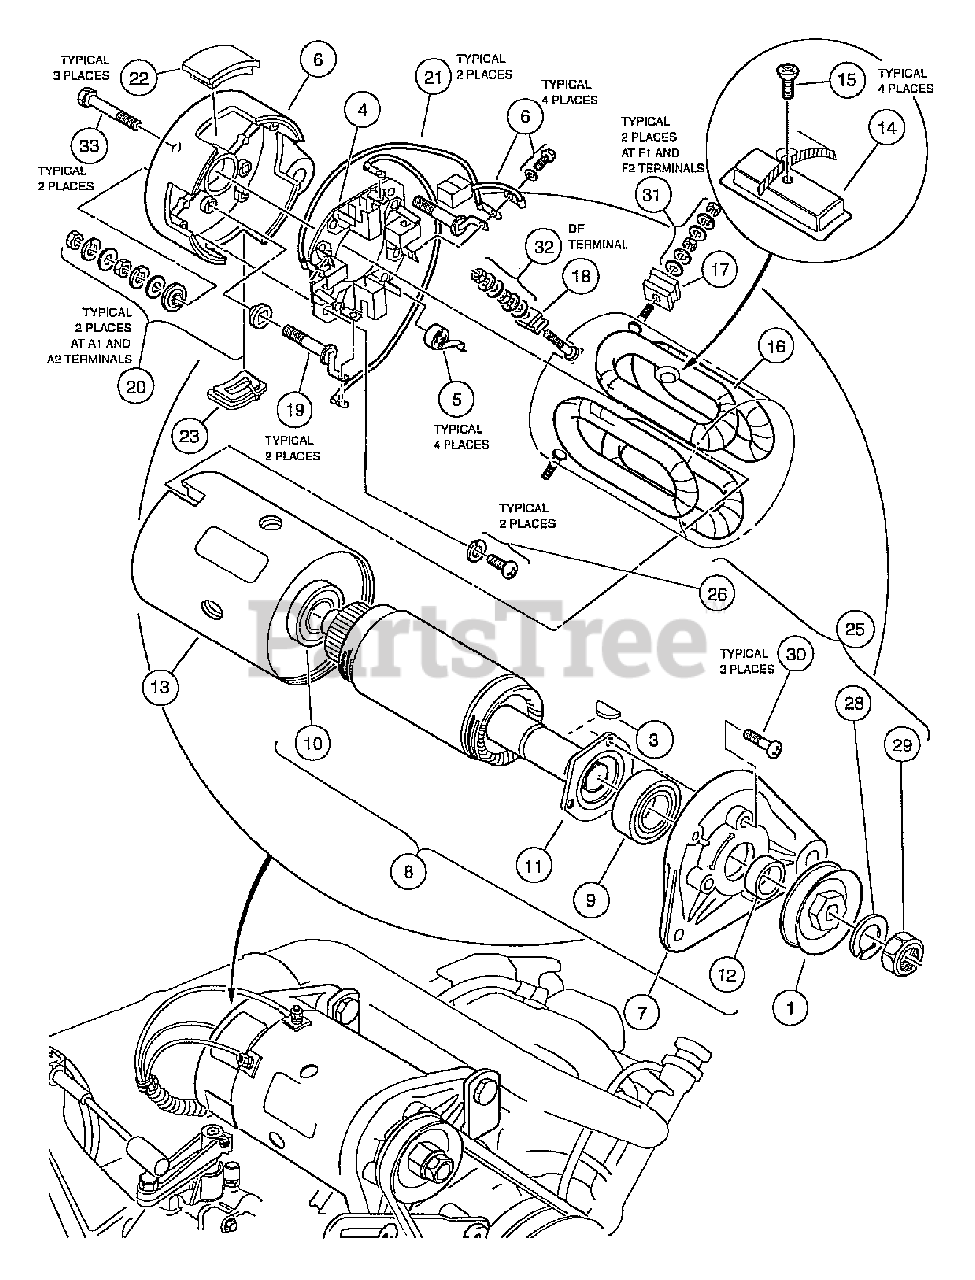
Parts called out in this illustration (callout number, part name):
1	Pulley, Starter/Generator
2	Starter-generator (cw)
3	Key, Starter/Generator
4	Brush Holder Assembly (cw)
5	Brush Spring Set
6	Brush and Screw Set (cw)
7	Front Bracket
8	Armature
9	Bearing, Output Shaft Ball
10	Bearing, Ball
13	Field Coil Housing
16	Field Stator Coil Assembly
17	F Insulator Set
18	DF Insulator
19	A Connector (cw)
20	Screw and Mold Assembly
21	Brush Connector Assembly (cw)
22	Cover Set
23	Brush Port Cover w/Drain
24	Rear Bracket (cw)
25	Nut and Screw Set
26	Brush Holder Asm Screw
27	Washer, M5 Flat
28	Washer, M14 Lock
29	Nut, Hex, M14 x 2
30	Screw, M5 x 0.8 x 18mm
31	Nut and Washer Set
32	Nut and Washer Set
33	Through Bolt Set
